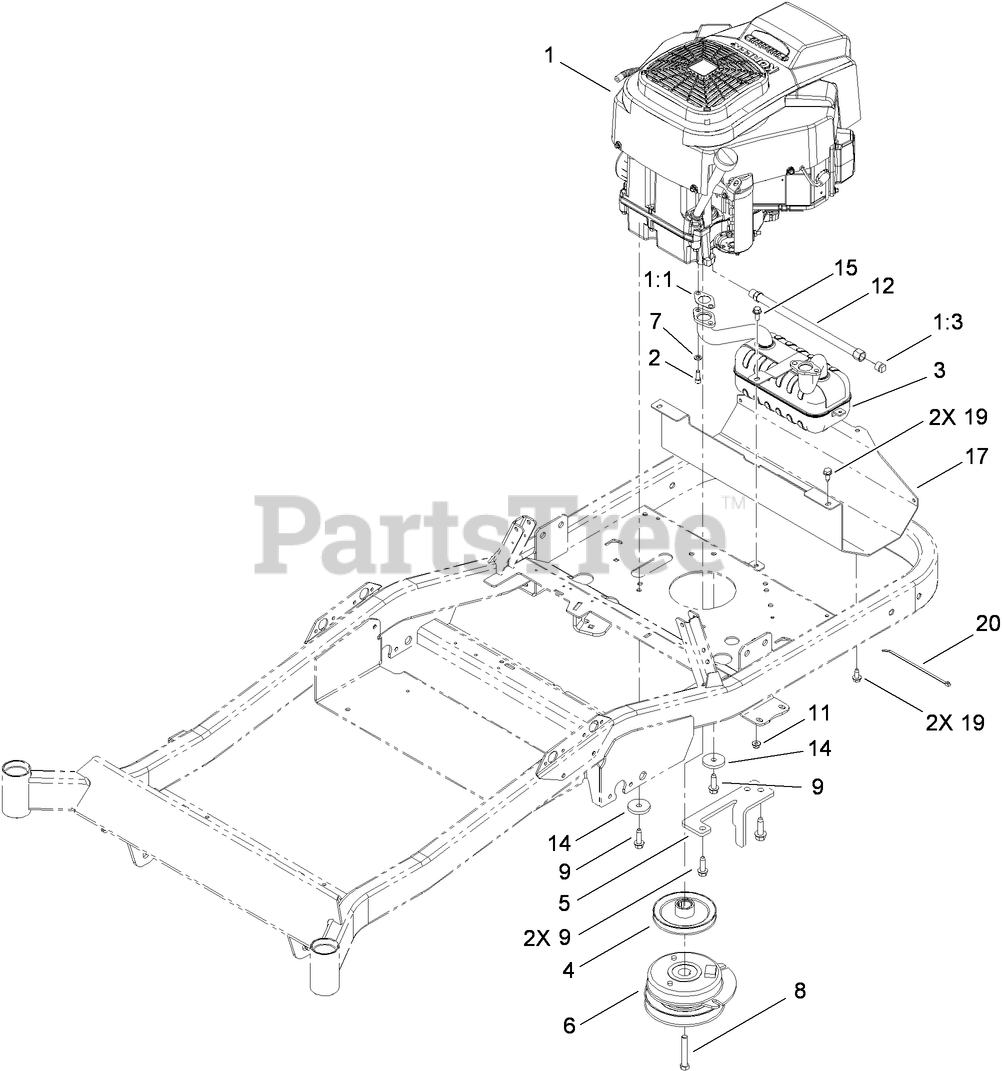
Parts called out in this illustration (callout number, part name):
1:1	GASKET-EXHAUST
1:3	PLUG-PIPE, SQH
2	SCREW-HSH
3	MUFFLER-TWIN, KOHLER
5	BRACKET-STOP, PTO
6	CLUTCH-PTO
7	WASHER-LOCK
8	SCREW-HH
9	SCREW-THD
11	NUT-HF, NI
12	HOSE-DRAIN, OIL
14	WASHER-PLAIN
15	SCREW-HHF
17	SHIELD-HEAT
19	SCREW-HWHTF
20	TIE-CABLE
